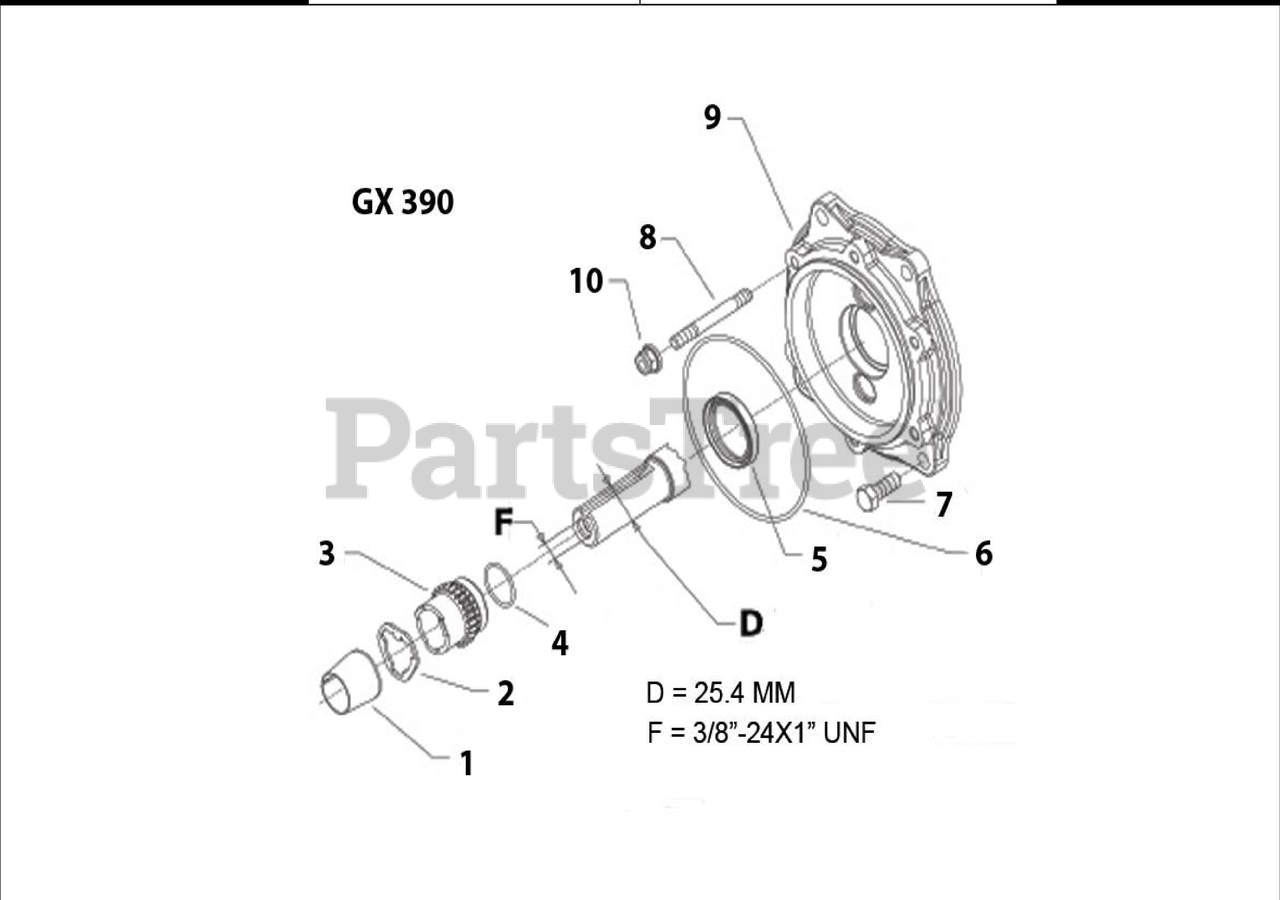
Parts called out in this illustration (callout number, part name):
1	TAPERED CENTRING BUSHING D=25.4
2	KEYED RETAINER
3	PUMP DRIVE GEAR
4	O-RING 2100 (25.12X1.78)
5	OIL SEAL 35X47X7
6	O-RING 3450 (113.97x2.62)
7	SCREW TE 3/8X1
8	STUD BOLT M8X73X14X20 8G
9	ENGINE FLANGE GX390
10	SELFLOCK NUT M8
